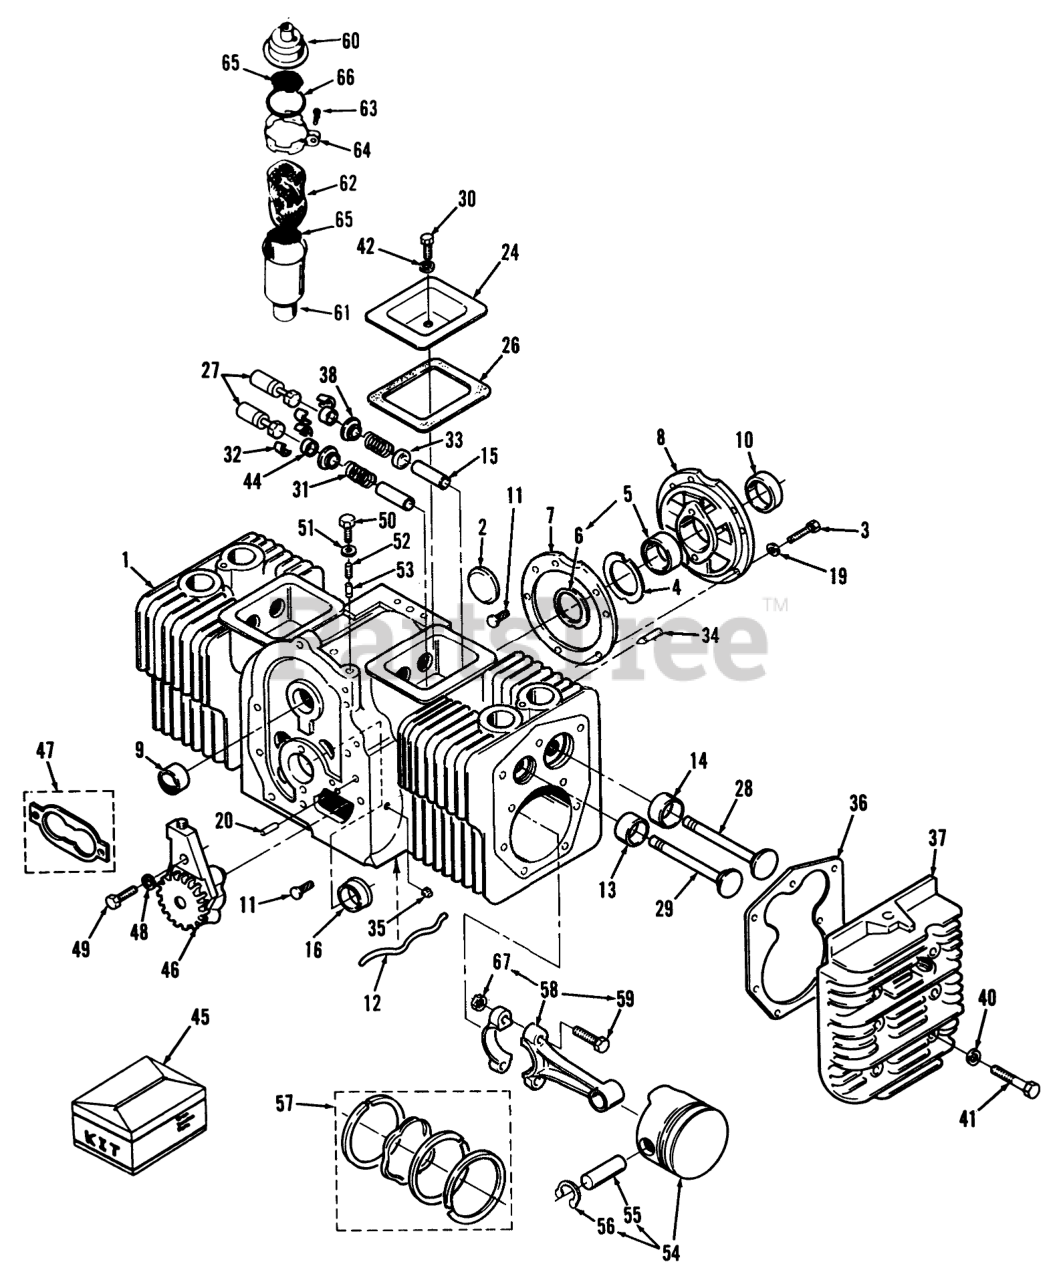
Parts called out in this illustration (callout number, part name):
1	Short Block
2	Plug
3	Screw
5	Bearing, Crankshaft-Rear (Includes Thrust Washer)
6	Thrust Washer
7	GASKET
8	Plate-Bearing
9	Standard
11	PIN-DRIVE
12	Oil Tube
13	Insert, Valve Seat-Exhaust
14	INSERT, VALVE SEAT-INTAKE
15	Exhaust Valve Guide
16	Bearing, Crankshaft-Front (Flanged)
19	Washer
20	PIN-GEAR COVER
24	VALVE-COVER L.H.
26	GASKET
27	Tappet, Valve
28	Intake Valve
29	Exhaust Valve
30	HHCS 1/4-20 X 1 3/4
31	Spring
32	VALVE SPRING LOCK
33	Seal, Valve-Intake
34	Screw
35	Plug
36	Gasket
37	HOUSING CYL RH
38	Washer
40	WASHER
41	Bolt
42	Washer
44	VALVE CAP
45	Kit, Gasket
47	GASKET KIT
48	WASHER-FLAT
49	SCREW - CAP HEX HEAD
50	SCREW-HH
51	Washer
52	Spring, Bypass
53	PLUNGER
54	Piston (Includes Pin and Retaining Rings)
55	Pin-Piston
56	Piston Pin
57	Kit, Ring-Piston
58	Rod, Connecting (Includes Bolt and Nut)
60	BREATHER-CAP AND VALVE
61	TUBE-BREATHER
62	FILTER
63	SCREW-TAPPING, ROUND HEAD
64	Clamp
65	SCREEN-BREATHER TUBE
66	SEAL - O-RING
67	Nut
